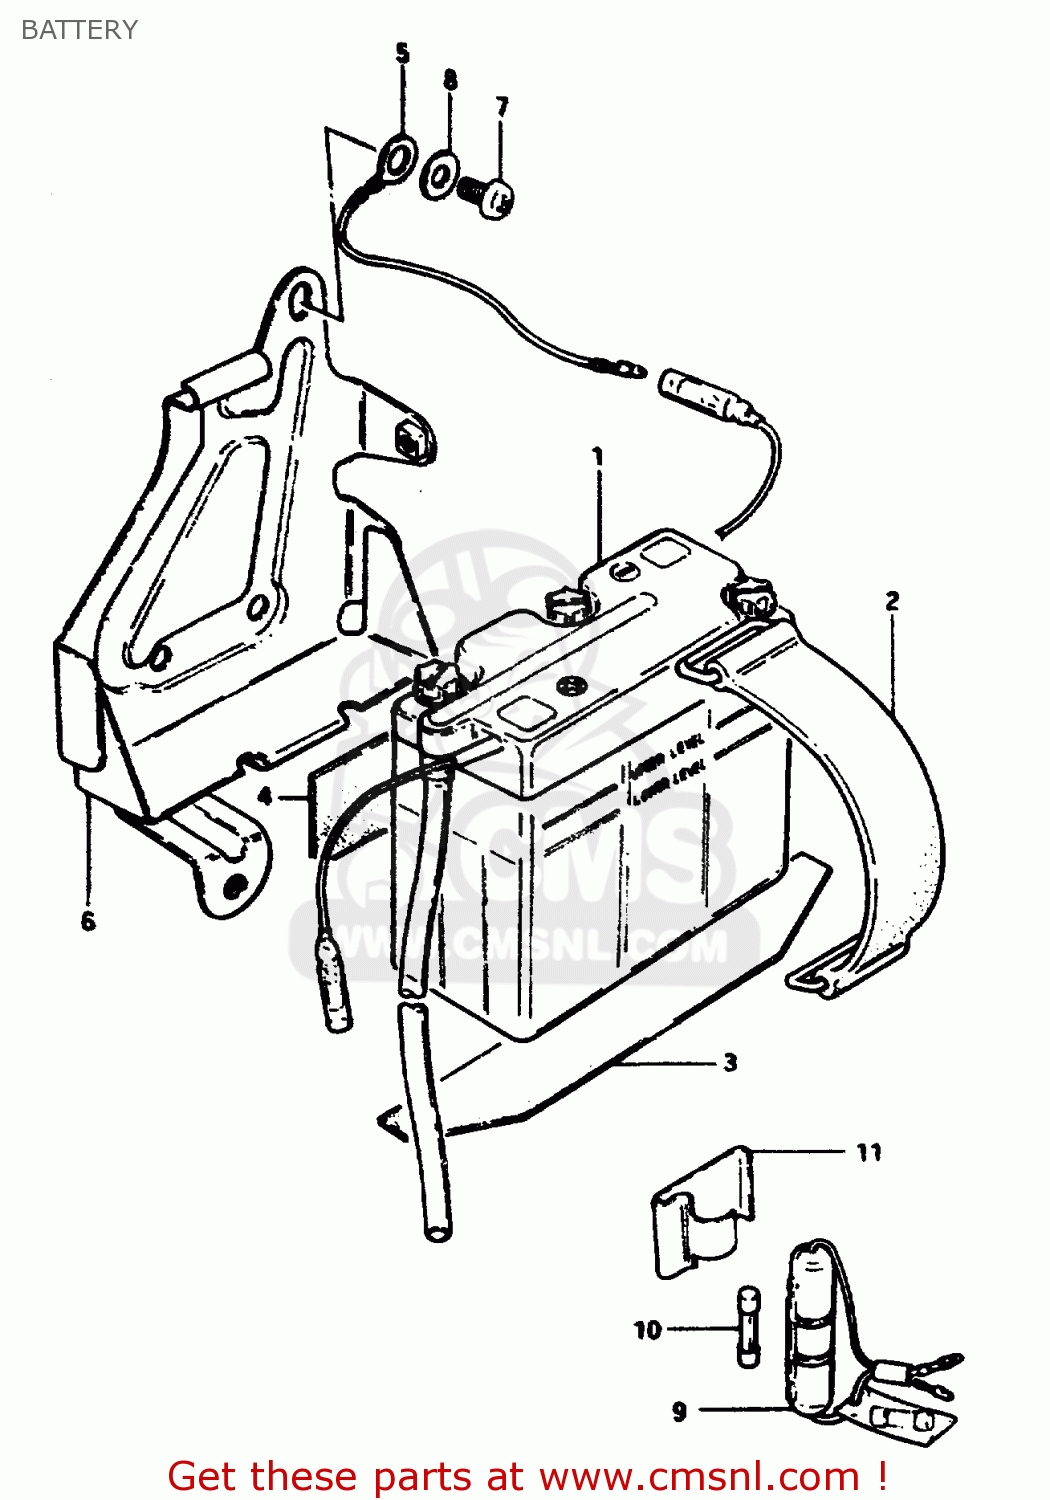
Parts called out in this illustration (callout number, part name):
1	BATTERY(6N4B-2A,6V4.2AH)
2	BAND
3	PROTECTOR,BATTERY
4	PROTECTOR(30X80X2)
5	LEAD WIRE
6	HOLDER, BATTERY
7	SCREW 6X12
8	WASHER
9	BOX ASSEMBLY,FUSE
10	FUSE(10A)
11	HOLDER,FUSE CASE
